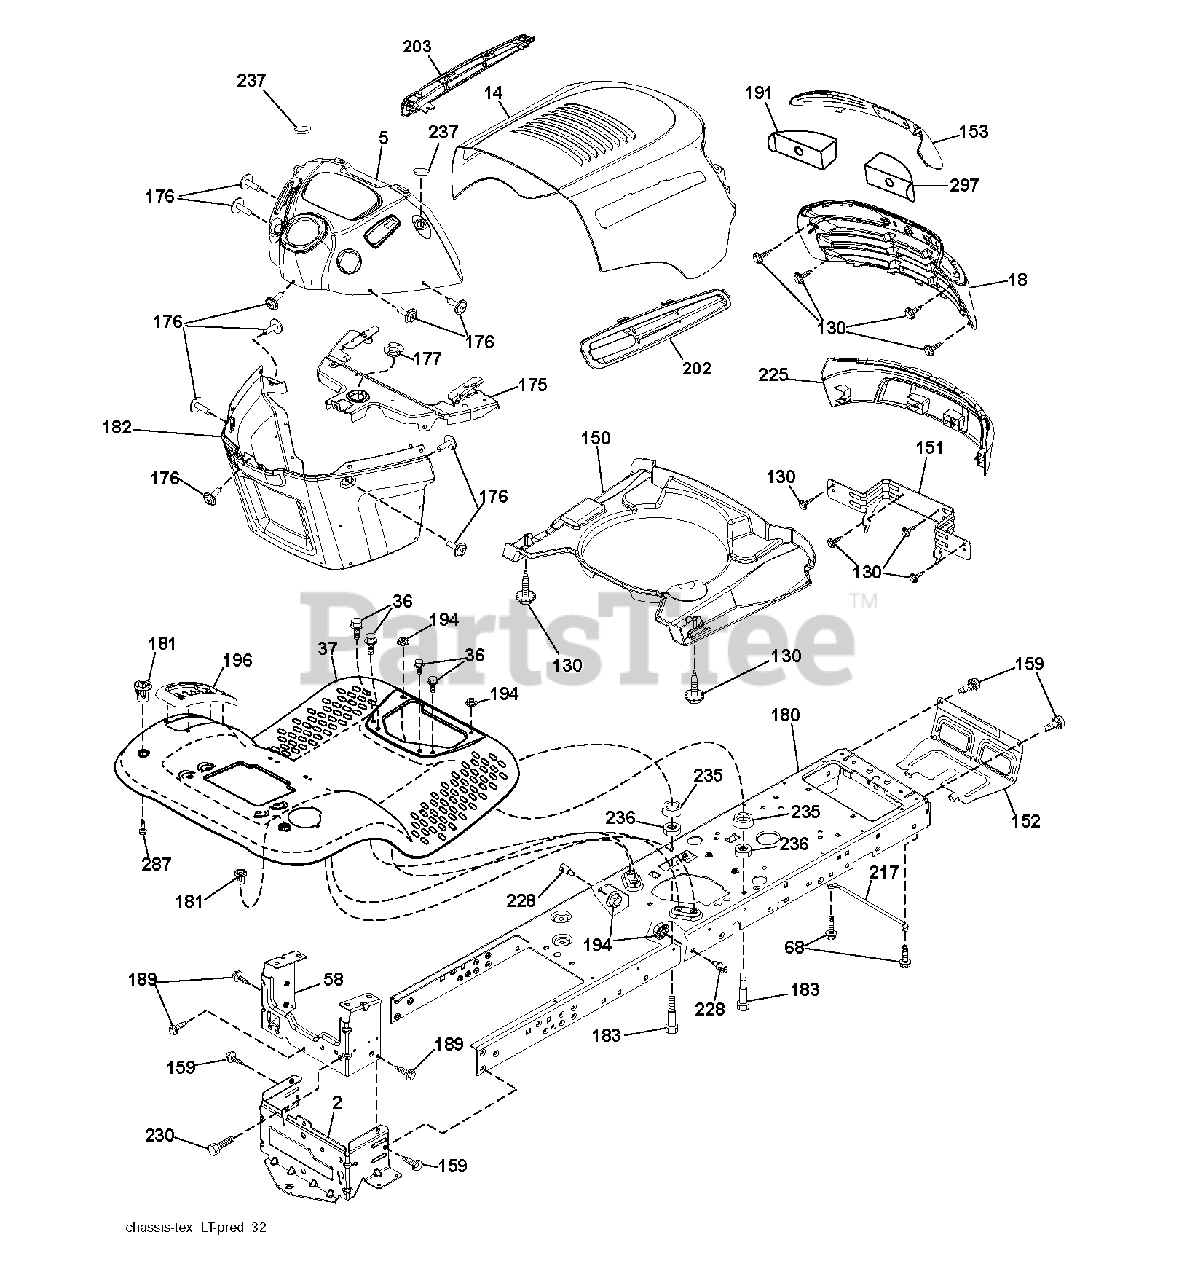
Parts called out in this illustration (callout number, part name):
36	SCREW 5/16"
58	DRAWBAR UPPER 2PC SMALL FENDER
130	SCREW.#10 X 0.750.BOS THREAD
151	BRACKET.PIVOT.ALPHA.LT
152	SHIELD.BROWNING/DEBRIS
159	SCREW, 3/8-16X3/4
162	SCREW.HI-LO.CONSOLE
175	CROSSMEMBER
176	SCREW.#10-24X5/8.RN.QU
177	BUSHING STEERING
180	CHASSIS.STAMPING.LT/GT
181	FEND/FTRST.PCH.CPH.NFW
182	DASH.LWER.PREDATOR/HUSQ.LT
183	BOLT.5/16-18X1-1/4 FULL.THREAD
189	SCREW
191	REFLECTOR.INSERT.PRED.LH.LT
194	NUT LOCK HEX FLANGE 5/16-18
196	CONSOLE.ASM.DECKLFT.BL/RBT.TLT
217	ROD.PIVOT.HOOD
228	STUD.FASTNER.W/ANTI-ROTATE
235	SPACER FENDER
236	NUT.CENTERLOCK.5/16-
237	PLUG.MOUNT.CARGO.BLK
297	INSERT.REFLECT.PREDATOR.LT.RH
